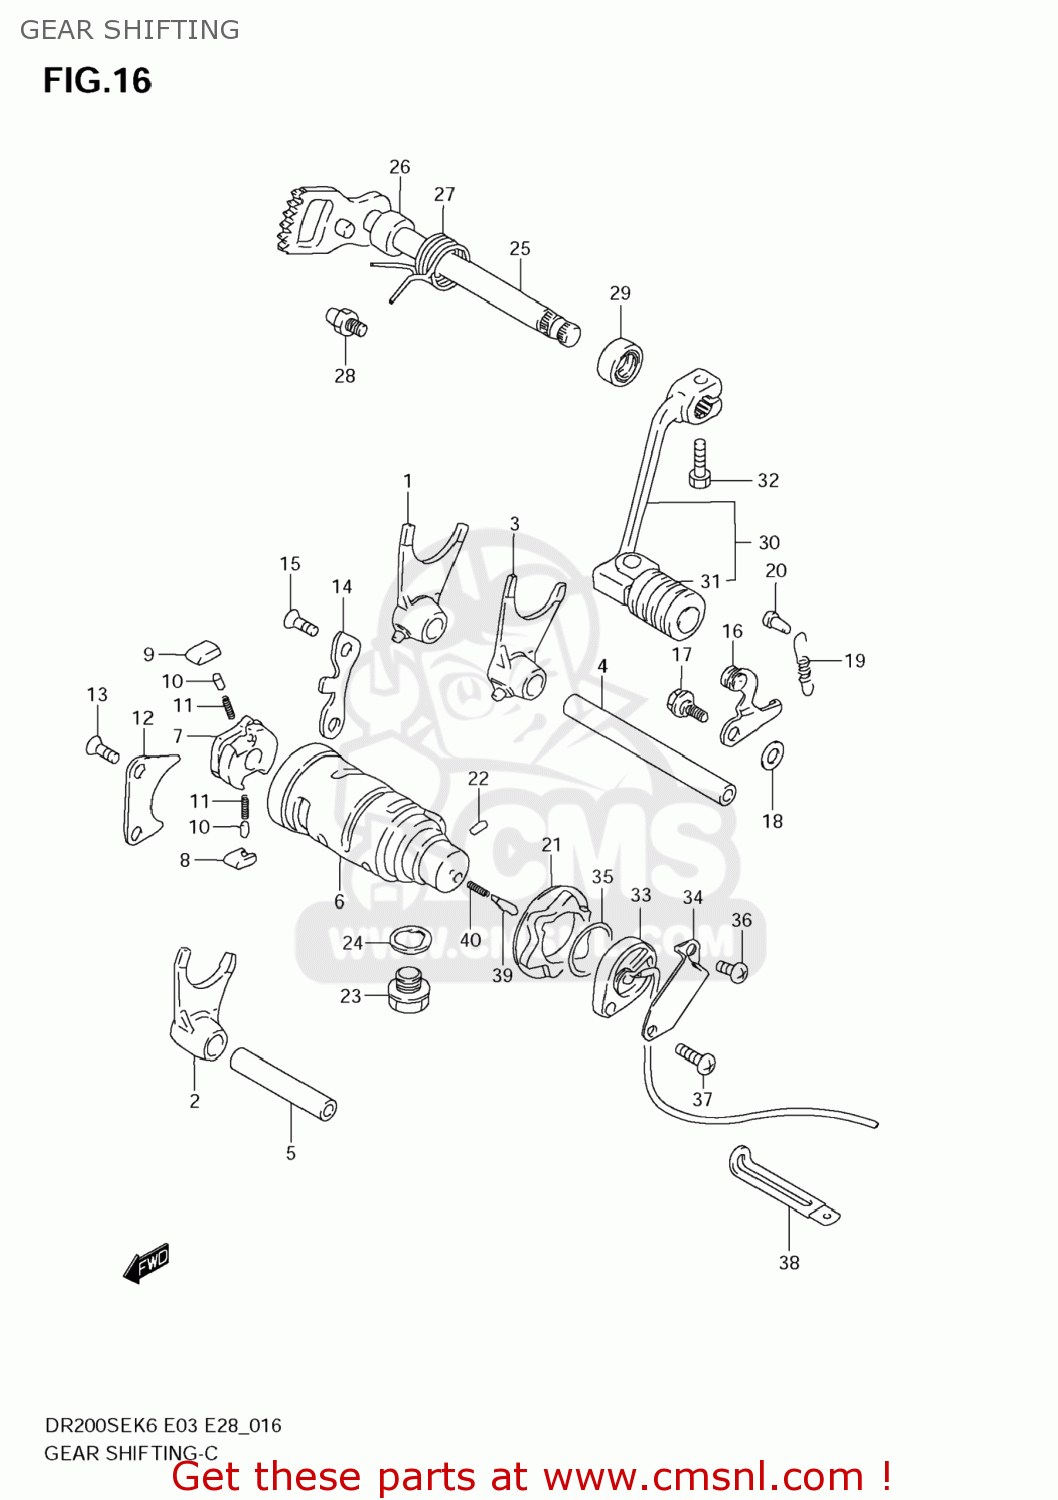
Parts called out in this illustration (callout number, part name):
1	FORK,GEAR SHIFT NO.1
2	FORK,GEAR SHIFT NO.2
3	FORK,GEAR SHIFT NO.3
4	SHAFT,GEAR SHIFT FORK(L:109)
5	SHAFT,GEAR SHIFT FORK NO.2
6	CAM,GEAR SHIFT
7	GEAR,GEAR SHIFT CAM DRIVEN
8	PAWL,GEAR SHIFT NO.1
9	PAWL,GEAR SHIFT NO.2
10	PIN(5X8)
11	SPRING
12	LIFTER,GEAR SHIFT POLE
13	SCREW(6X12)
14	GUIDE,GEAR SHIFT CAM
15	SCREW(6X12)
16	STOPPER,GEAR SHIFT CAM
17	BOLT(6X14.6)
18	WASHER
19	SPRING
20	RIVET
21	PLATE,GEAR SHIFT CAM STOPPER
22	PIN
23	PLUG(14X12)
24	GASKET(13.8X18.8X4.8) (NAS)
25	SHAFT,GEAR SHIFT
26	SPACER(12X20X15.3)
27	SPRING
28	STOPPER,GEAR SHIFT ARM
29	OIL SEAL
30	LEVER ASSY,GEAR SHIFT
31	RUBBER,GEAR SHIFT PEDAL
32	BOLT
33	BASE ASSY,NEUTRAL SW TERMINAL
34	PROTECTOR,GEAR SHIFT SW
35	O RING(D:2.4,ID:21.8)
36	SCREW
37	SCREW
38	CLAMP(L:45)
39	PIN(5X15.5)
40	SPRING
